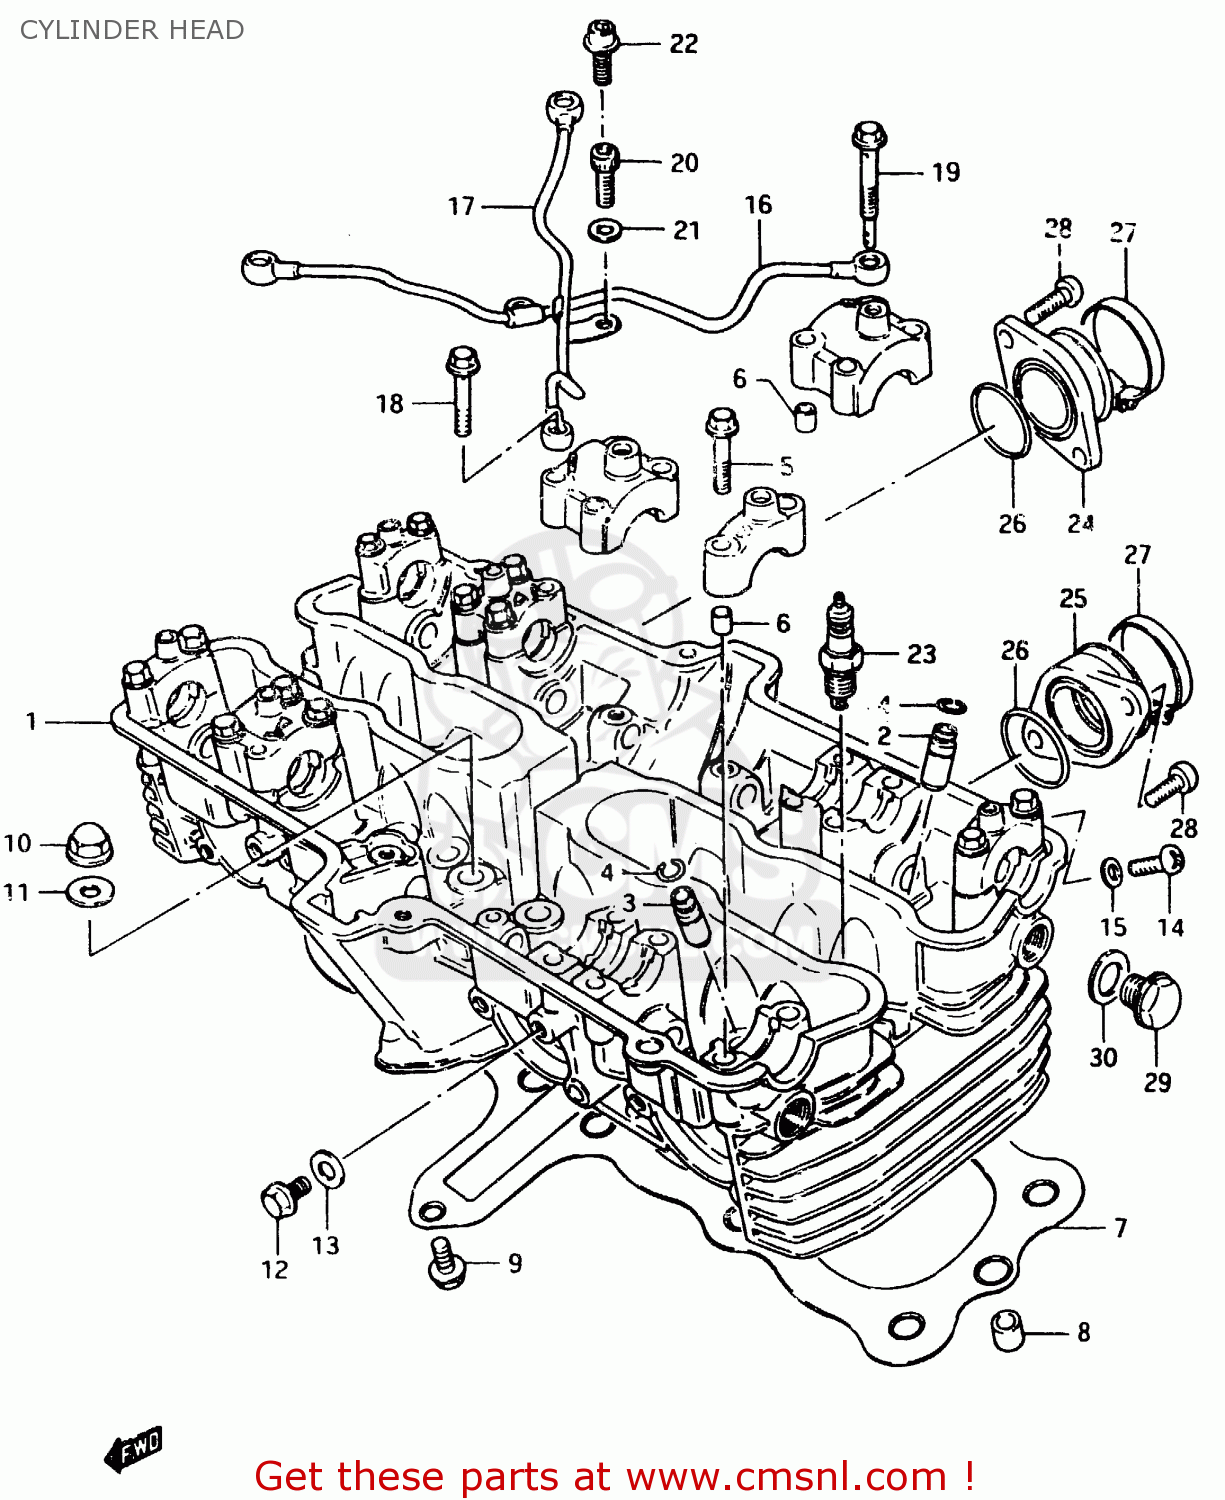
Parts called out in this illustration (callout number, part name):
1	HEAD ASSEMBLY,CYLINDER
2	GUIDE,INTAKE VALVE
3	GUIDE,INTAKE VALVE
4	RING,SNAP
5	BOLT(6X39)
6	PIN(6.2X8X11)
7	GASKET,CYLINDER HEAD (MCA)
8	PIN
9	BOLT
10	NUT
11	GASKET(10.5X22X2) (NAS)
12	BOLT
13	GASKET(6.2X13X1.2) (NAS)
14	SCREW
15	GASKET(5.3X9.3X1.2) (NAS)
16	PIPE,OIL CYLINDER HEAD
17	PIPE,OIL CYLINDER HEAD
18	UNION
19	BOLT,UNION
20	BOLT
21	WASHER
22	BOLT
23	SPARK PLUG X24ES-U
24	PIPE,INTAKE
25	PIPE,INTAKE
26	O-RING
27	CLAMP
28	SCREW
29	PLUG
30	GASKET(14X19.2X2) (NAS)
